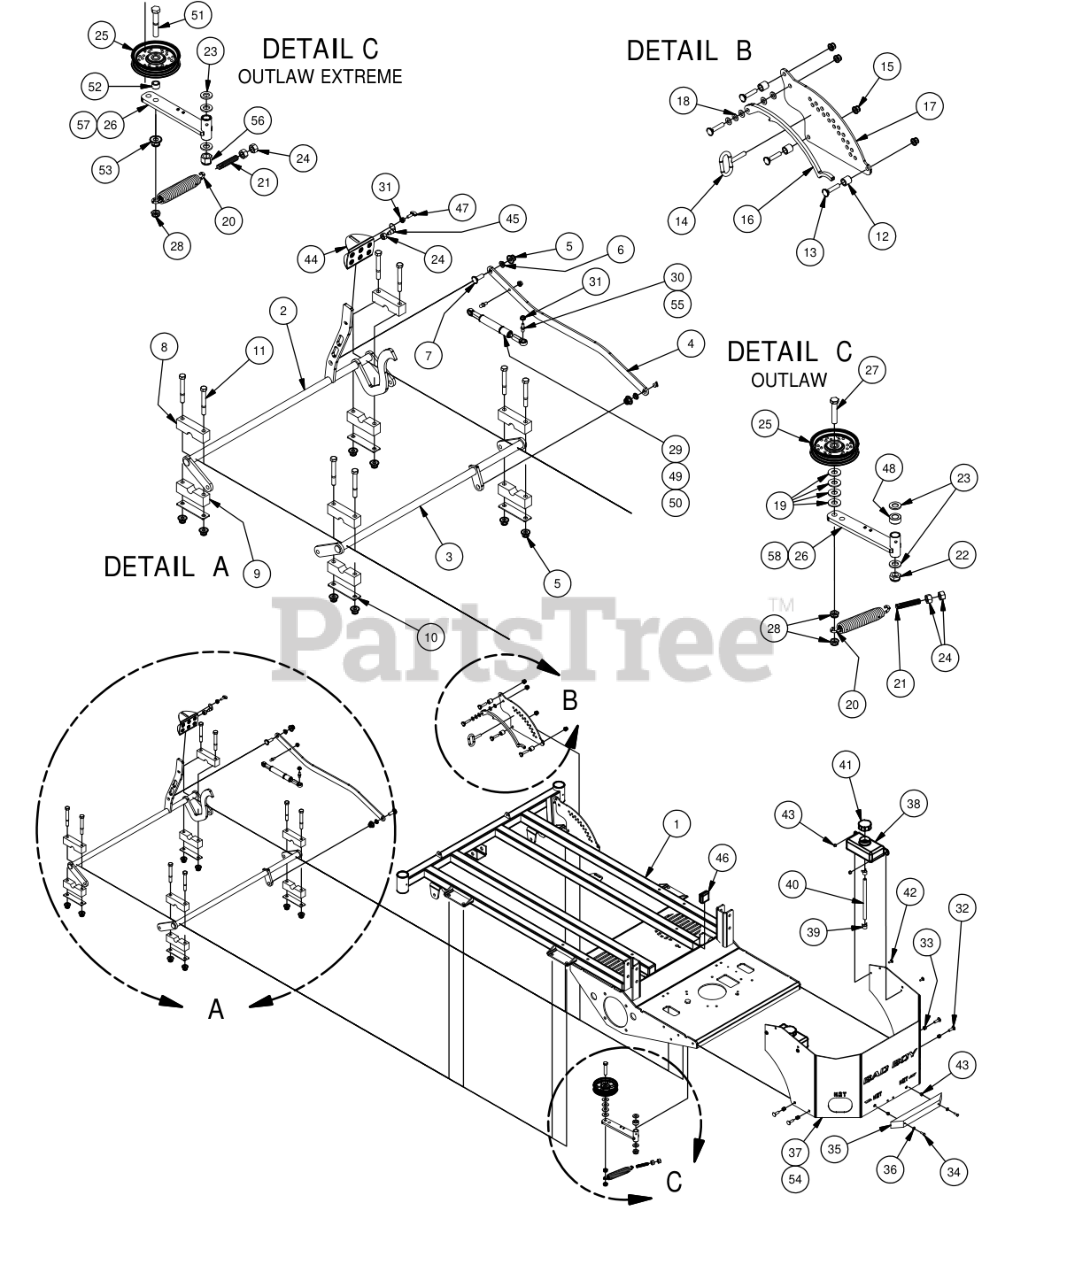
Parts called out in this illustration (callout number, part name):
1	2015 Standard/Extreme Outlaw Frame
2	2015 Outlaw Act Bar Assembly (Front)
3	2015 Outlaw Act Bar Assembly (Rear)
4	Outlaw Deck Linkage Rod
5	1/2-13 Nylon Flange Nut
6	Bushing- SF-1620-4
7	1/2 x 1-1/2 Carriage Bolt
8	Two Piece Pillow Block (Male)
9	Two Piece Pillow Block (Female)
10	Two Piece Pillow Block Strap
11	1/2" x 4" Bolt (Grade 8)
12	Spacer 3/4 OD x 1/2 ID x 3\4 Length
13	3/8 x 1 3/4 Carriage Bolt
14	Deck height lever pin
15	3/8" Nylock Flange Nut
16	Outlaw Deck Lever Lock
17	Outlaw Height Indicator Plate (Outer)
18	.390 x .750 x .062 Nylon Washer
19	1/2" Brass Washer (Base Only)
20	2009 Deck/Pump Idler Spring
21	All Thread-Pump Idler Tensioner
22	5/8" Nylock (1/2 Jam) (Base Only)
23	.630 ID Plastic Washer
24	1/2" Hex Nut
25	4 3/4 Idler Pulley - ABFI-76
26	Deck Idler
27	1/2" x 3" Hex Bolt (Base Only)
28	1/2" Nylock Nut (1/2 Jam)
29	200 lb Gas Spring- 54" Deck outlaw
30	10mm Damper Ball Stud-Steering
31	5/16" Flange Nut
32	3/8" x 1 1/4" Carriage Bolt
33	3/8 Nylock Nut
34	1/4-20 x 1-1/4 GR 5 Hex Bolt
35	14" Rubber Bumper
36	1/4" Flat Washer
37	2015 Outlaw Rear Plate
38	Expansion Tank Outlaw
39	5/8 Wire Clamp-Outlaw Only
40	5/8 Braided Hose
41	Hydraulic Tank Cap
42	1/4" x 3/4" Carriage Bolt
43	1/4-20 Nylon Insert flange Nut
44	Outlaw Deck Lift Pedal
46	2X2 Frame Plug
47	5/16-18 x1 Thumb Screw Zinc
48	5/8" x 1/" Collar W/One Set Screw
49	250 lb Gas Spring -61" Deck Outlaw
50	300 lb Gas Spring - 72" Deck Outlaw
51	1/2 x 2-1/2 Hex Bolt (Extreme Only)
52	1/2" x 1/2 Spacer (Extreme Only)
53	1/2"-13 Nylon Flange Nut (Extreme Only)
54	2016 Outlaw/XP Rear Cover (36 Vanguard Only)
55	13mm Damper Ball Stud for 72" Deck only
56	5/8 Std NC Nylock Nut (Extreme Only)
57	Pump Idler Assy - Outlaw Extreme Components:25,26,28,51,52,53
58	Pump Idler Assy - Base Outlaw Components:19,25,26,27,28
